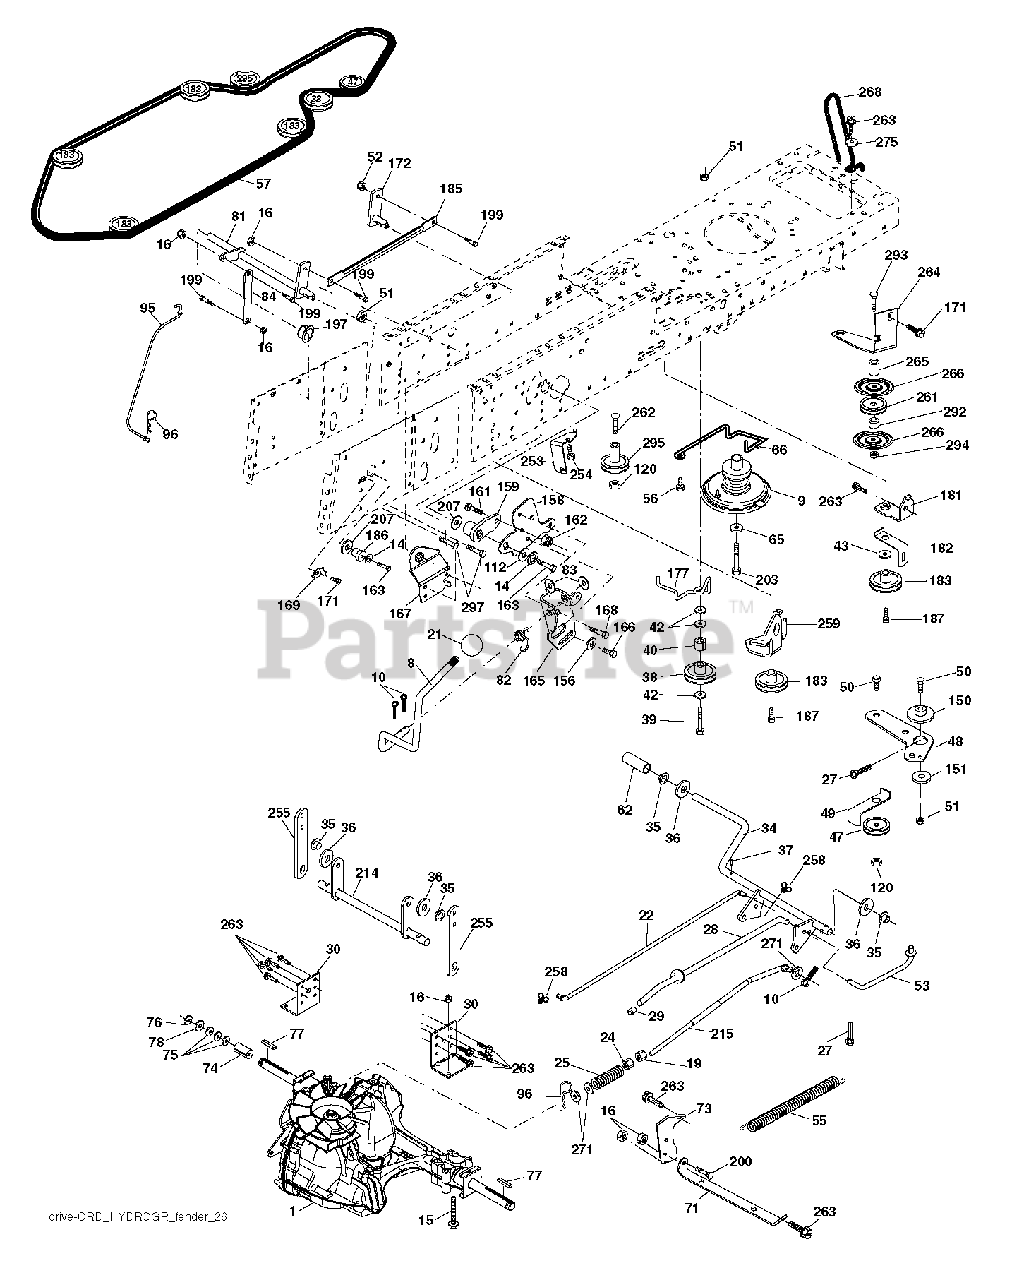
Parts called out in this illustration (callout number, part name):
8	ROD SHIFT FENDER ADJUST LT
10	PIN COTTER
14	LOCKWASHER
15	BOLT HEX 5/16-18 GR 5
16	NUT.71038.31-18.HEX.NYLOCK
19	NUT
21	KNOB T (1/2-HOLE)
22	ROD
24	NUT
25	SPRING BRAKE ROD
27	COTTER PIN
28	ROD, PARKING BRAKE
29	PLUNGER CAP
30	BRKT, TRNSXLE MNT 20"
34	SHAFT, FOOT PEDAL
35	BEARING.NYLON
36	WASHER LT
37	DRIVE PIN
38	PULLEY.FLAT
42	WASHER
43	WASHER T
47	IDLER PULLEY
48	BELLCRANK, CLUTCH
49	RETAIN BELT
50	BOLT.3/8-16X1.50
52	LOCKNUT
53	LINK.CLUTCH.7.66.2005
55	SPRING, RETURN LT
56	SCREW.3/8-16
57	V-BELT 113"
62	PEDAL COVER T
65	LOCKWASHER
66	KEEPER BELT ENGINE
71	STRAP TORQUE LH HYDRO
73	STRAP TORQUE RH HYDRO
74	SPACER AXLE
77	SQUARE KEY
81	ASM.CROSS.SHAFT.REAR.CRD.0510
82	SHIFT SPRING
83	WASHER
84	LINK.PNT.TRANSAXLE.0510.CRD
95	LINK
96	RETAINER M
112	WASHER LT
120	NUT LOCK FLG 3/8-16 UNC
150	BUSHING.BELLCRANK.GRD.DR
151	WASHER 12/32X2X10GA
156	WASHER.SRRTD.5/16
158	BRACKET.SHIFT.MOUNT
161	BOLT
162	NUT.CROWNLOCK.1/4
163	BOLT
165	BRACKET.PIVOT.LEVER
166	CAPSCREW.HXHD.FLG.5/16-18X.625
167	BRACKET.SUPT.SHIFT.CRD
168	BOLT.SHOULDER.5/16-18X
169	PLATE.FASTENING.CROSS.SHAFT
171	SCREW LT
172	LINK
181	BRACKET
182	BELT GUIDE
183	PULLEY.V-IDLER.
185	LINK
186	HUB.TAPERED.ROUND.CRD
187	BOLT.5/16-18X1.25
197	NYLINER SNAP 5/8" ID
199	BOLT SHOULDER 5/16-18 UNC
200	BOLT
203	BOLT.HEX.7/16-20 X 5
207	WASHER NYL
214	LEVER
215	ROD
254	SCREW 3/8-16X1
255	SHAFT
258	CLIP RETAINER
259	BRACKET
261	FLAT IDLER PULLEY
263	SCREW, 3/8-16X3/4
264	BRACKET.IDLER.CHASS.NORAM.2010
266	PROTECTOR
268	GUARD MUFFLER
271	WASHER
275	WASHER
292	SPACER
293	BOLT.RDHD SQNK 3/8-16 X 3-1/2
294	Hex Nut, 3/8-16
295	PULLEY IDLER COMPOSITE
297	SCREW LT.3/8-46X5/8
